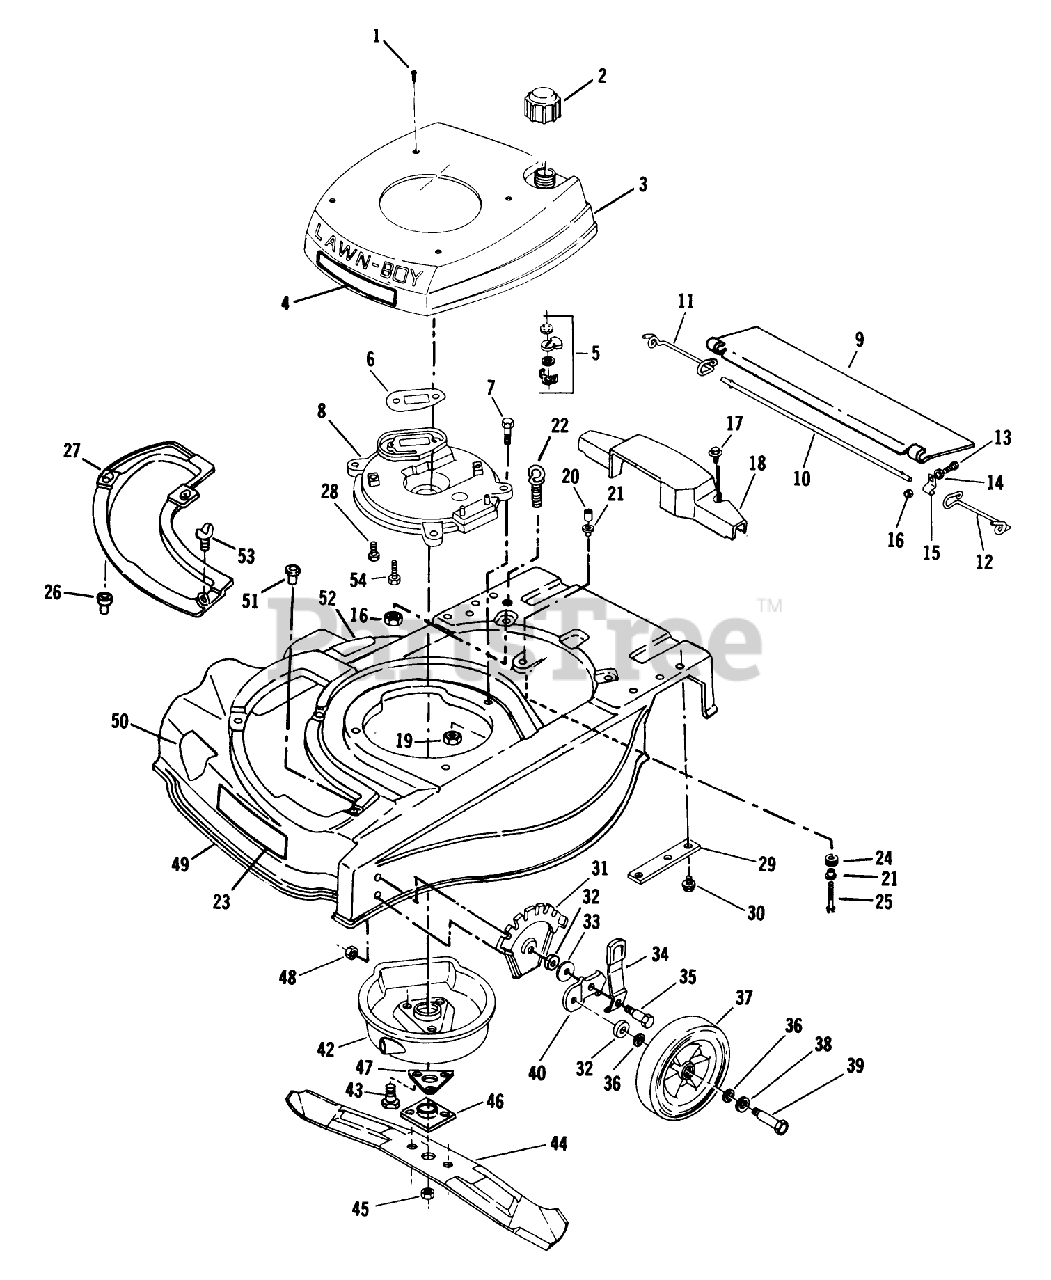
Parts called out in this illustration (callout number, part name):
1	SCREW LAWRENCE
2	FUEL CAP & INSERT
7	SCREW-HH
8	PLATE,MUFFLER F
10	ROD T/SHIELD ADV WIRE
11	SPRING;TRAILING SHIELD RH
12	SPRIG T/SHLD ASOC
14	WASHER F
15	CLAMP ROD KMC
16	LOCKNUT E
17	SCREW SEMS TRM HEX HD
19	NUT-LOCK F
20	SPACER
21	SPACER ECK PRES
22	BOLT-EYE
30	SCREW
31	PLATE HGT ADJ TRO
32	WASHER WROUGHT
33	WASHER
34	KNOB & SPRING
35	BOLT
36	WASHER
37	WHEEL & TIRE KIT
38	SPACER
39	BOLT WHEEL
41	SCREW V
43	SCREW
45	NUT-BLADE
46	PLATE AND COLLAR ASM
47	SUPPORT F
48	LOCKNUT
53	WING SCREW LAWRE
